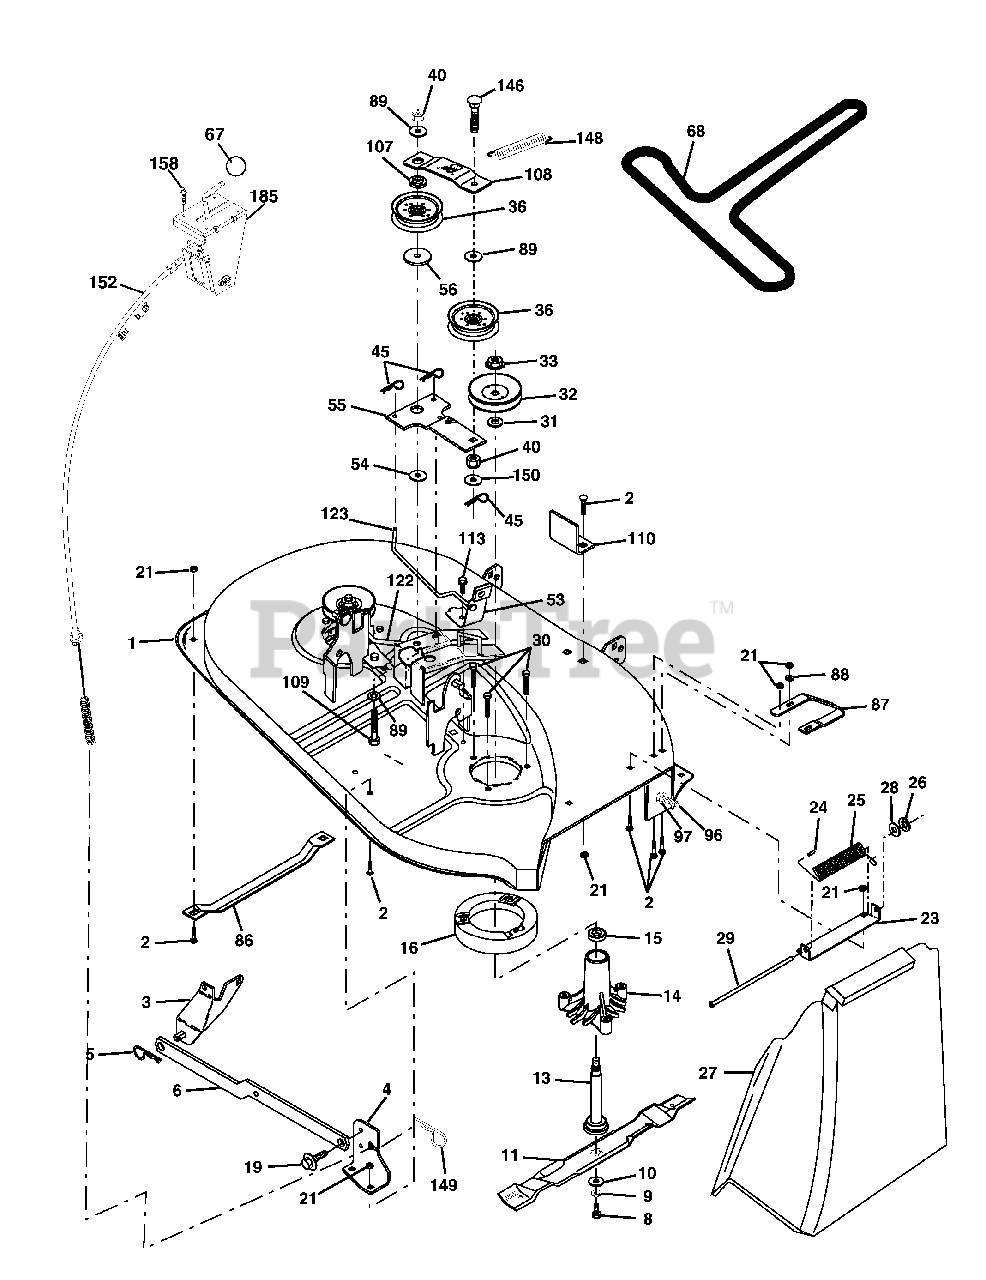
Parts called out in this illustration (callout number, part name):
1	Mower Housing Assembly
2	Bolt Carriage 5/16-18 x 3/4
3	Bracket Asm Fr. Sway Bar
4	Bracket Deck Sway Bar 38"/42"
5	Retainer Spring
6	Bar Sway Deck
8	Bolt 3/8-24 x 1.25 Gr. 8
9	Washer, Lock 3/8
10	Washer, Hardened
11	Blade Mower
13	Shaft Assembly, Mandrel, Vented
14	Housing, Mandrel, Vented
15	Bearing, Ball, Mandrel
16	Stripper, Vented Mower Deck
19	Bolt, Shoulder
21	Nut
23	Bracket, Mower Deflector
24	Cap, Sleeve
25	Spring, Torsion, Deflector
26	Nut, Push
27	Shield, Deflector
28	Washer 11/32 x 5/8 x 16 Ga.
29	Rod, Hinge
30	Screw Thdrol.
31	Washer, Spacer
32	Pulley, Mandrel
33	Nut, Toplock
36	Pulley, Idler, Flat
40	Nut, Crownlock 3/8-16 unc
45	Retainer
53	Brake Assembly
54	Washer, Hardened
55	Idler Arm Assembly
56	Spacer, Retainer
67	Knob
68	V-Belt, 42" Mower
86	Runner, LH
87	Runner, RH
88	Washer 11/32 x 3/4 x 16 Ga.
89	Washer 13/32 x 13/16 x 11 Ga.
96	Bolt 3/8-16 x 1-1/4 Mulcher
97	Nut Centerlock 3/8-16 unc
107	Spacer Retainer
108	Stiffener, Idler Arm
109	Bolt, Hex Hd 3/8-16 x 2-1/2
110	Upstop Deck Front 38"
113	Screw 5/16-1/ x 3/4
122	Rod, Brake LH
123	Rod, Brake RH
146	Bolt Carriage Idler
148	Spring Return Idler
149	Retainer Spring Yellow
150	Washer 9/32 x 3/4 x 10 Ga.
152	Clutch Cable 38"/46"
158	Screw Hex Thd Cut 1/4-20 x 1/2
185	Head Asm Cable Clutch
